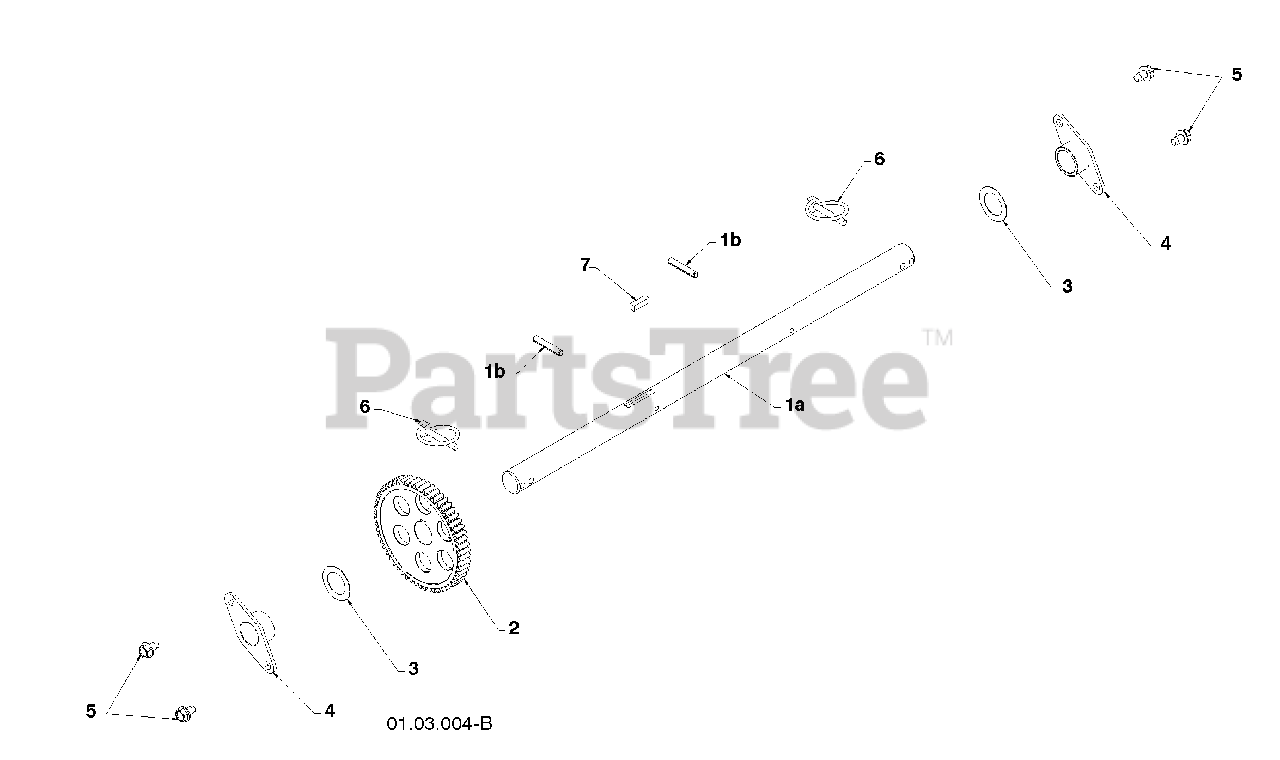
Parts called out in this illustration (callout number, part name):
1	(assy of 1a,1b) AXLE ASSEMBLY
2	GEAR
3	THRUST WASHER
5	BOLT 5/16-18 X .500
7	SQUARE KEY
